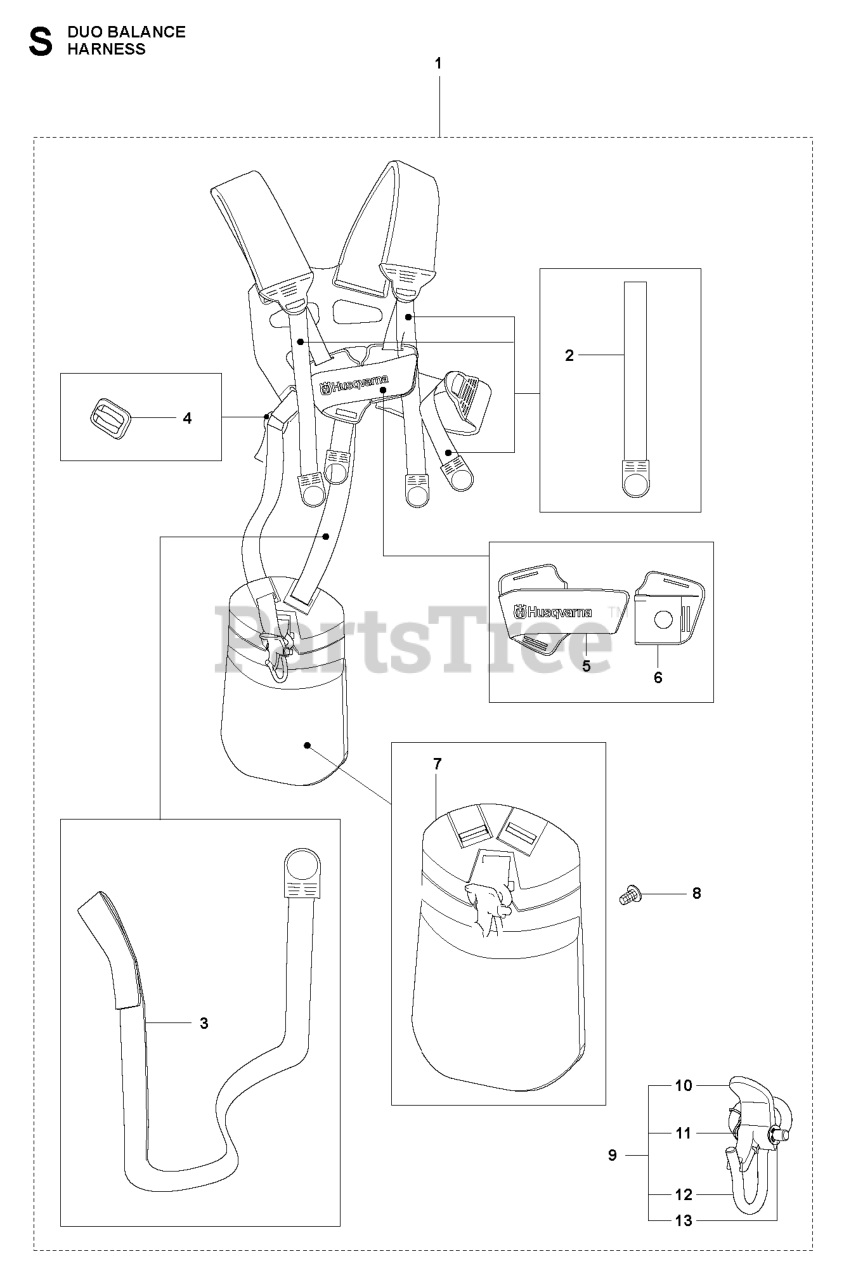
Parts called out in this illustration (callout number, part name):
1	Harness
4	RP CLIP
5	FRONT PIECE
6	FRONT PIECE
9	HOOK
10	CATCH *
11	SPRING LOCKING
12	HOOK
